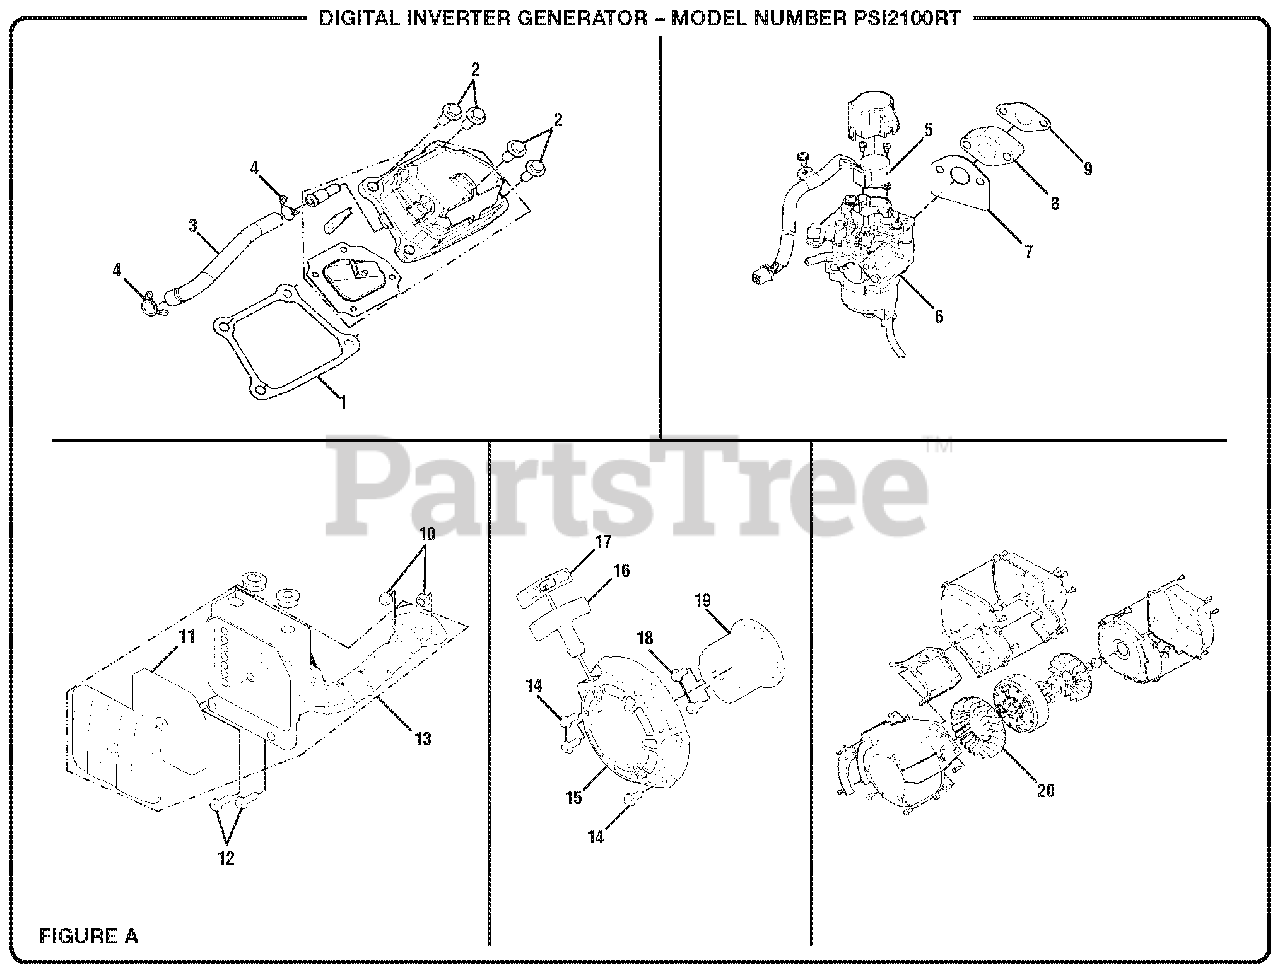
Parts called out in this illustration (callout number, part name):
1	Cylinder Head Cover Gasket
2	Bolt (M6 x 16 mm, Flange Hd.)
3	Engine Vent Hose
5	Stepper Motor Assembly
6	Carburetor Assembly
7	Intake Seat Gasket
8	Carburetor Seat Adapter
9	Adapter Rear Gasket
10	Flange Nut (M6)
11	Air Filter Element
12	Bolt (M6 x 12 mm, Flange Hd.)
13	Air Filter Assembly
14	Bolt (M6 x 16 mm, Flange Hd.)
15	Recoil Starter Disc Set
16	Recoil Handle
17	Recoil Handle Cover
18	Bolt (M6 x 12 mm, Flange Hd.)
19	Recoil Starter Driving Disc
20	Front Fan
